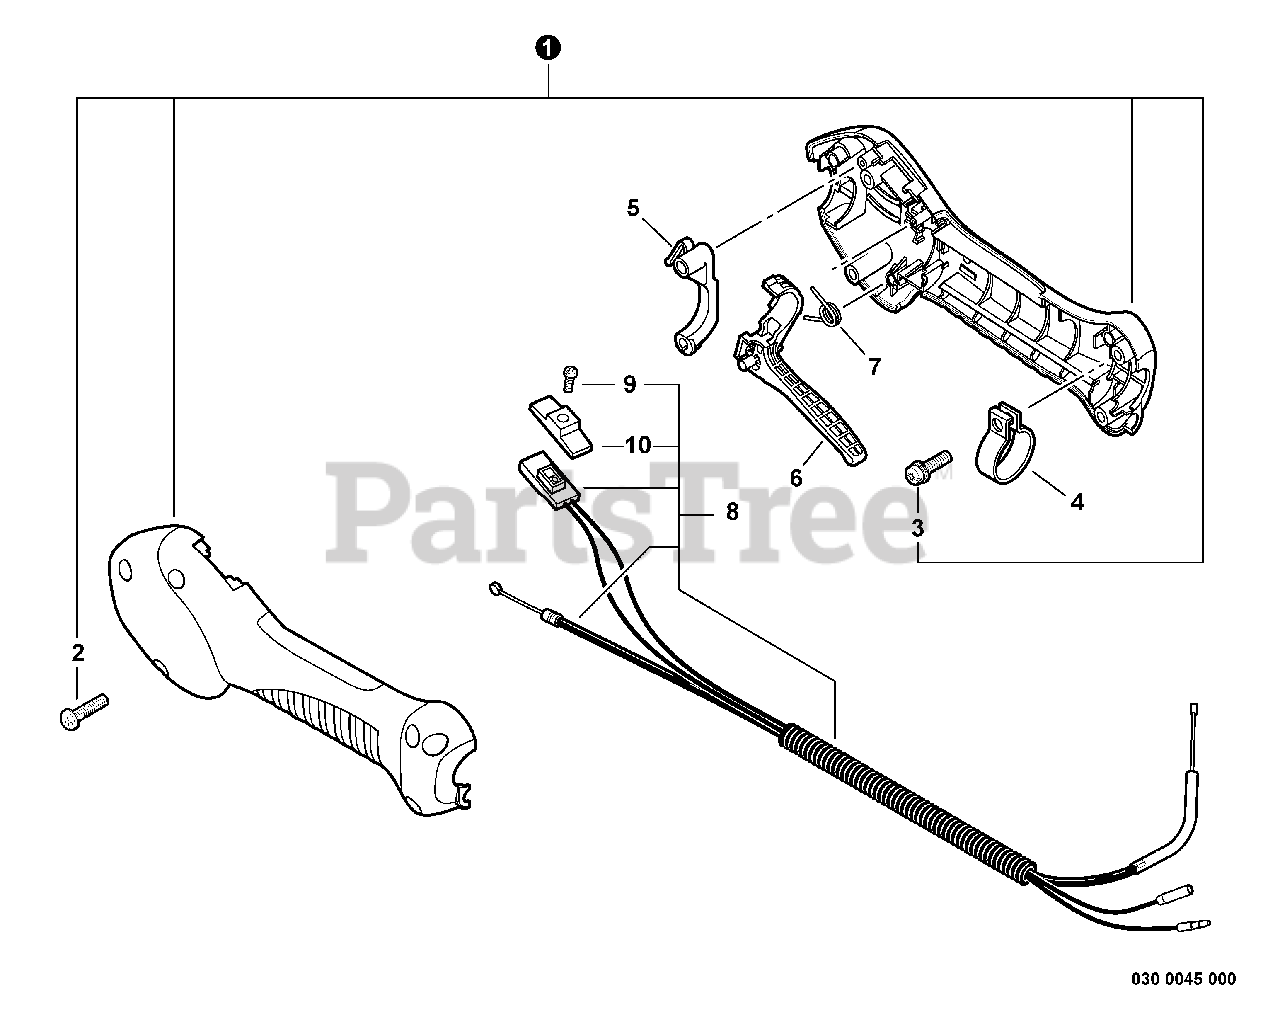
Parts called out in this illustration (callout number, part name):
1	CONTROL HANDLE KIT
2	SCREW - 5X20
3	SCREW - 5X20
5	LOCKOUT, THROTTLE
6	TRIGGER, THROTTLE
7	SPRING, TRIGGER
8	CONTROL CABLE ASSY
9	SCREW - 3X10
10	KNOB, SWITCH - ORANGE
